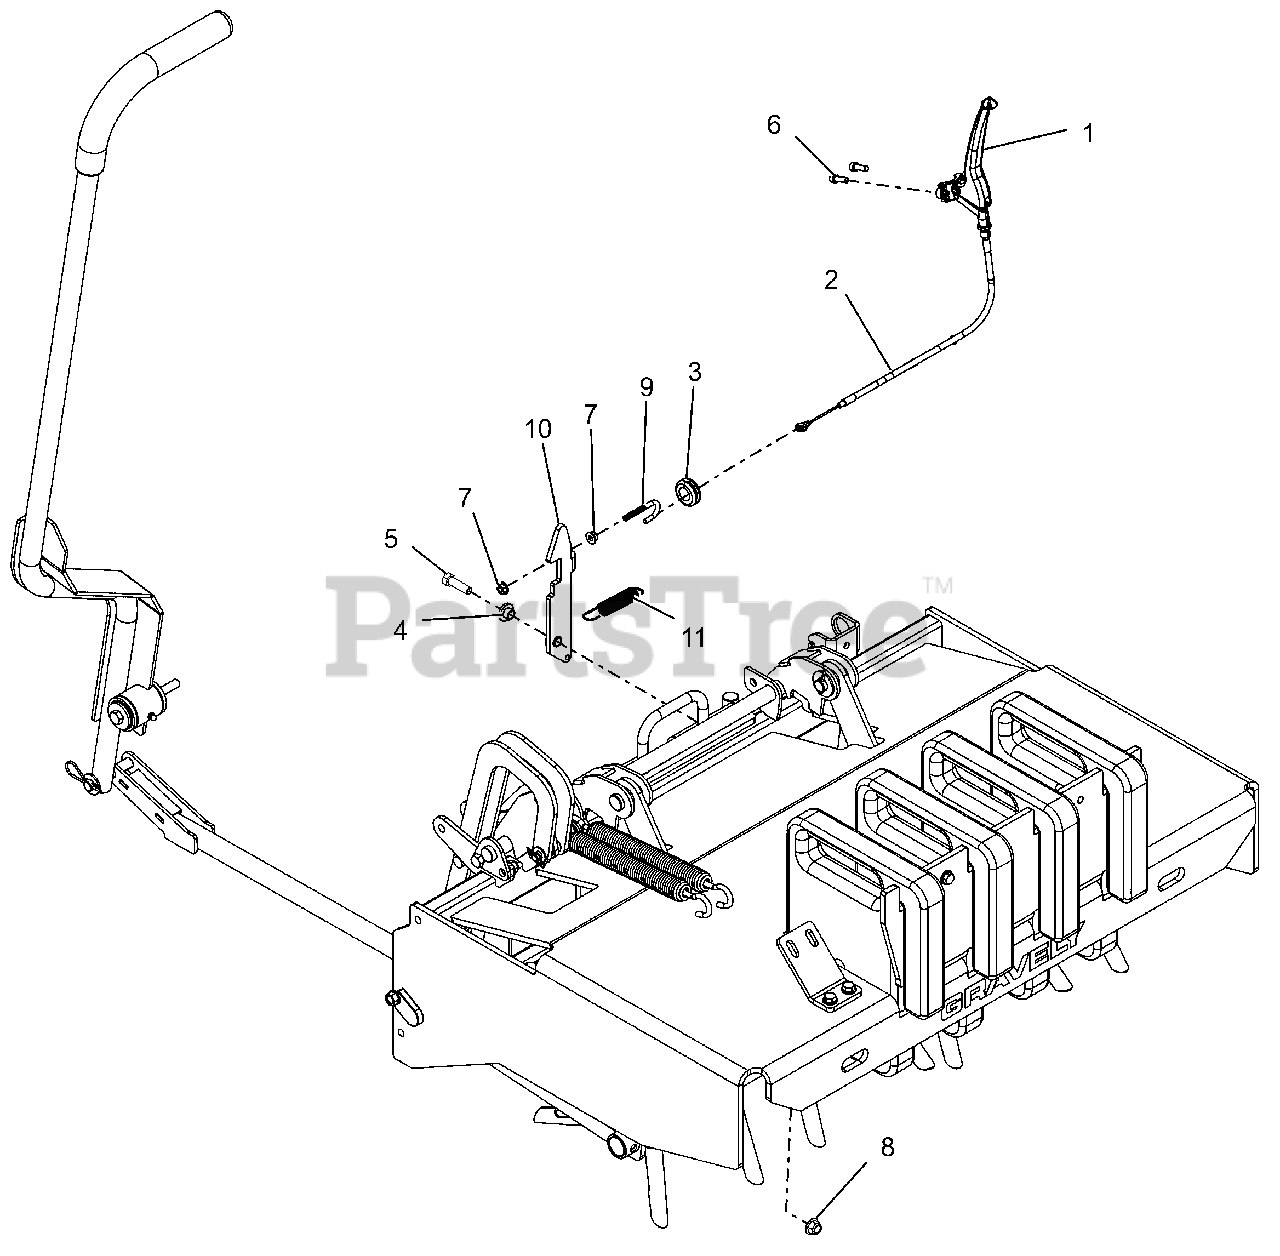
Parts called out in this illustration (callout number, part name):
1	HANDLE, ANGLE CONTROL
2	CABLE ASSY, BRUSH
3	GROMMET, SPLIT RUBBER
4	BSHG-FLG .385X.500X.875X.406
5	BLT, HEX .38-16X1.25 G5 ZCC
6	SCR, SKH M6-1 X 20 GR10.9 ZCC
7	NUT-SPNLK-FLG .25-20 ZC120
8	NUT,NYL-FLG .38-16 GF ZCC
9	BLT, J-HOOK .25-20X2.31 ZCC
10	EAR, LOCK - RED
11	SPRG, EXT .653 X .063 X 2.755
